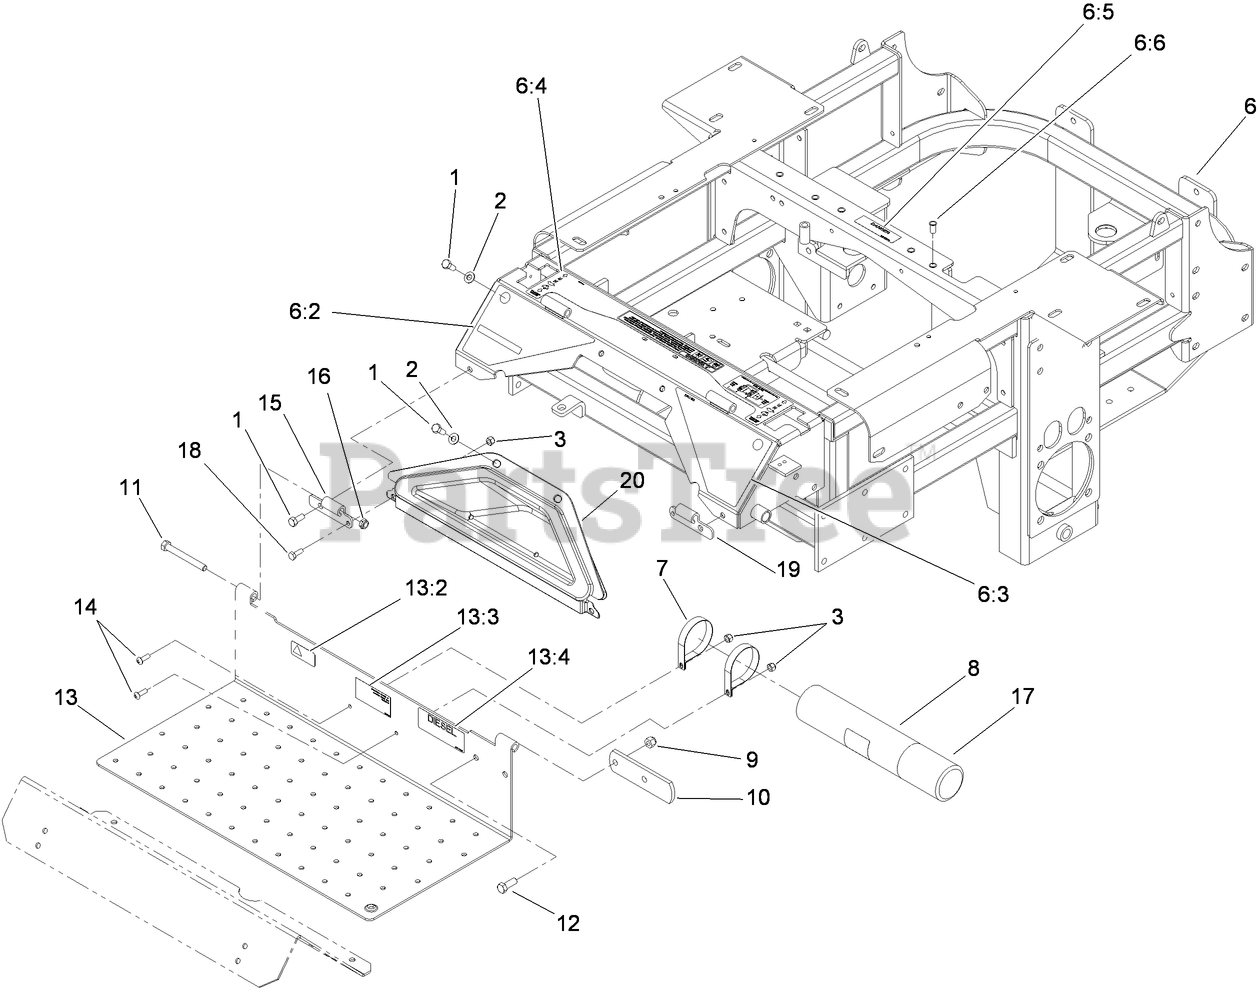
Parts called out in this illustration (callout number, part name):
1	SCREW-HH
2	WASHER-FLAT
3	NUT-LOCK, NI
6	TRACTION FRAME ASM
6:2	Decal-Warning
6:3	Decal-Danger
6:4	DECAL-CONSOLE, TOP
6:5	DECAL-COVER, MISSING
6:6	INSERT-THREADED
7	R-Clamp
8	TUBE-MANUAL
9	NUT-LOCK, NI
10	STOP-BRAKE, PARK
11	SCREW-HH
12	SCREW-HH
13	FLOOR PAN ASM
13:2	DECAL-PROTECTION, EAR
13:3	Decal-Location, Manual
13:4	DECAL-DIESEL, BIO-READY
14	SCREW-PRH
15	Hinge-Floorpan, LH
16	NUT-LOCK, NI
17	CAP-HOUSING
18	SCREW-HH
19	Hinge-Floorpan, RH
20	Pocket
